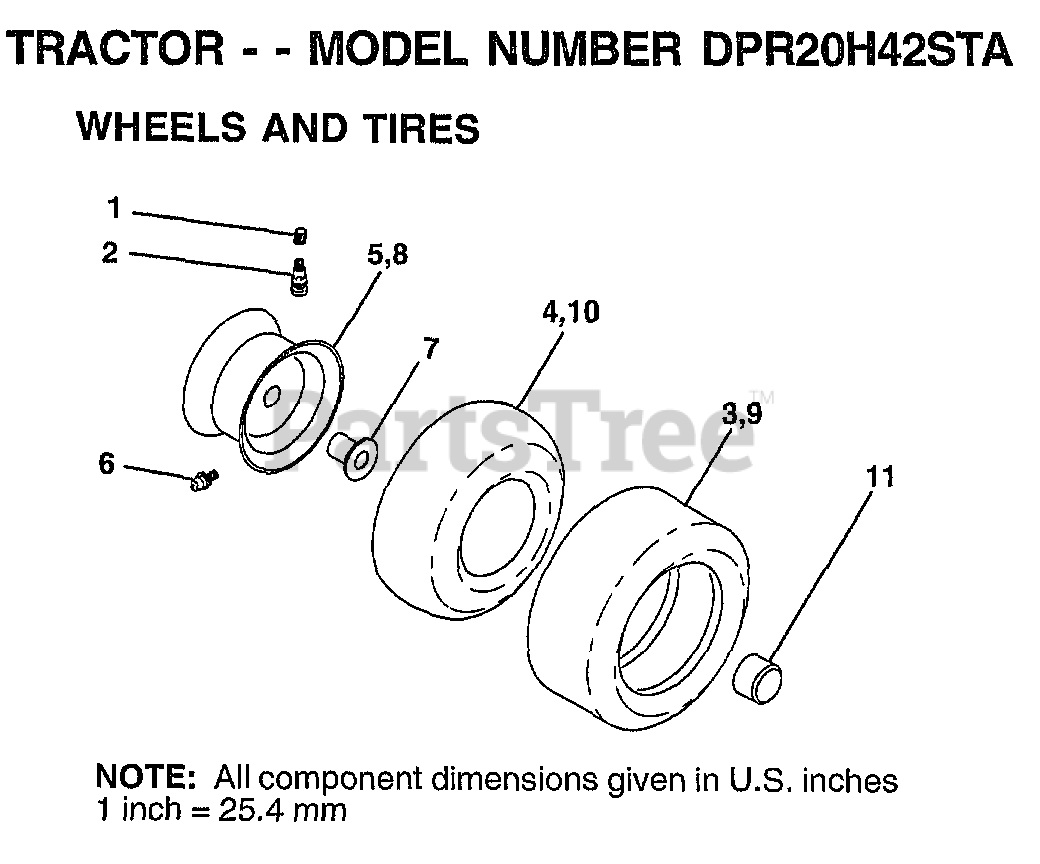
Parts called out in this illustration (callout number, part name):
1	VALVE CAP
2	VALVE STEM LT
3	TIRE
4	TUBE.5.3/4.5/6
5	RIM.FRONT.6.YELLO
6	FITTING LT
7	"FLANGE, BEARING"
9	TIRE
10	TUBE.18X9.5-8
11	HUB CAP
